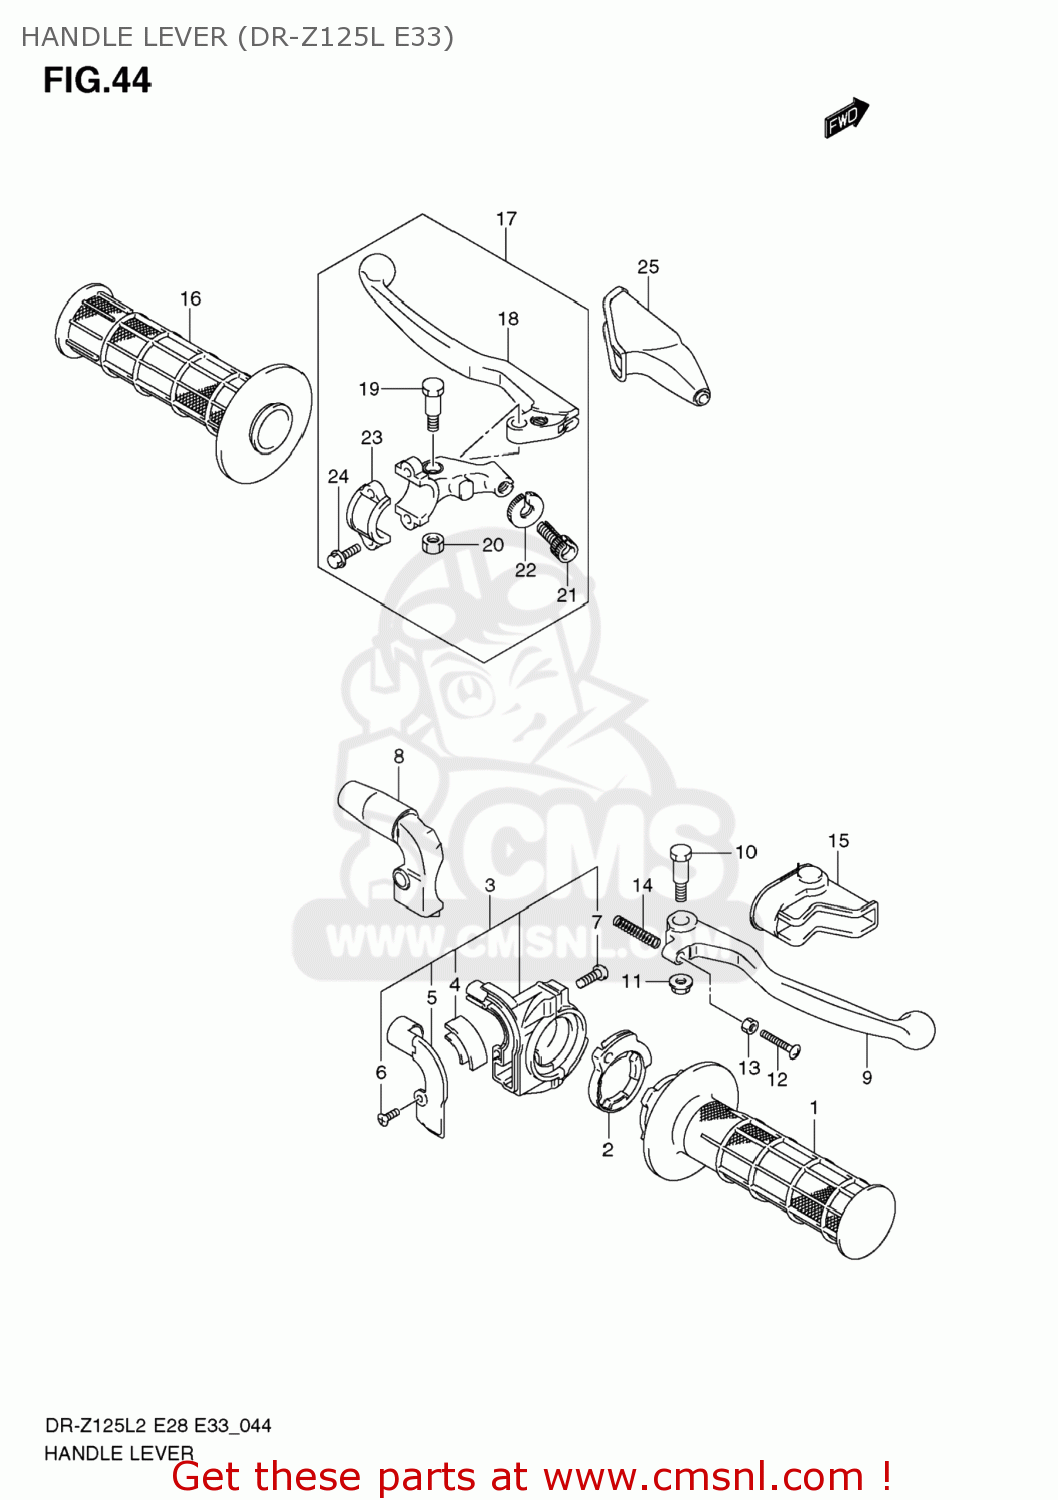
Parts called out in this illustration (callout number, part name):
1	GRIP,THROTTLE
2	ROTER,THROTTLE
3	CASE ASSY,THROTTLE
4	GUIDE
5	COVER
6	SCREW
7	SCREW
8	COVER,THROTTLE CASE
9	LEVER,BRAKE
10	BOLT,BRAKE LEVER
11	NUT
12	BOLT,ADJUST
13	NUT
14	SPRING,RETURN
15	COVER,BRAKE LEVER
16	GRIP,L
17	LEVER ASSY,CLUTCH
18	LEVER,CLUTCH
19	BOLT,LEVER PIVOT
20	NUT
21	ADJUSTER,WIRE
22	NUT,LOCK
23	BRACKET,CLUTCH LEVER HOLDER
24	BOLT,BRACKET
25	COVER,CLUTCH LEVER
